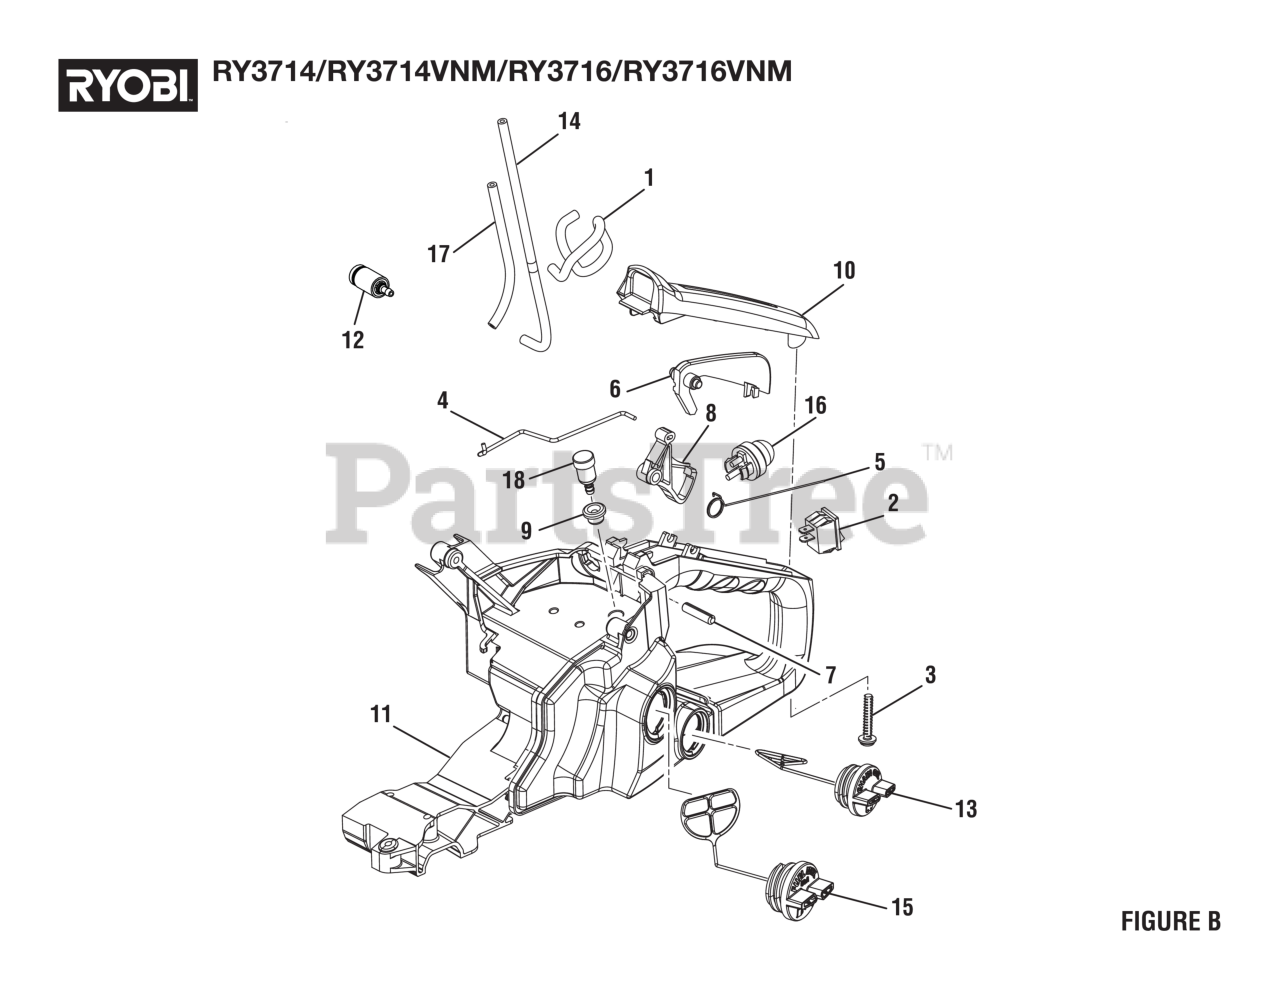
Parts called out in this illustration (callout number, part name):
1	Fuel Hose (Primer Assembly to Carburetor, 160 mm)
3	Screw (M5 x 27 mm, T25 Torx Pan Hd.)
4	Throttle Rod.
5	Throttle Spring
6	Safety Rock Arm
7	Spring Pin
8	Throttle Trigger
10	Grip Cover
11	Rear Handle Assembly
12	Fuel Filter Assembly
13	Oil Cap Assembly
14	LP-1500 Tubing (205.00 mm)
15	Fuel Cap Assembly
16	Primer Bulb
17	Fuel Hose (Primer Assembly to Tank, 153 mm)
18	Fuel Breather Assembly
